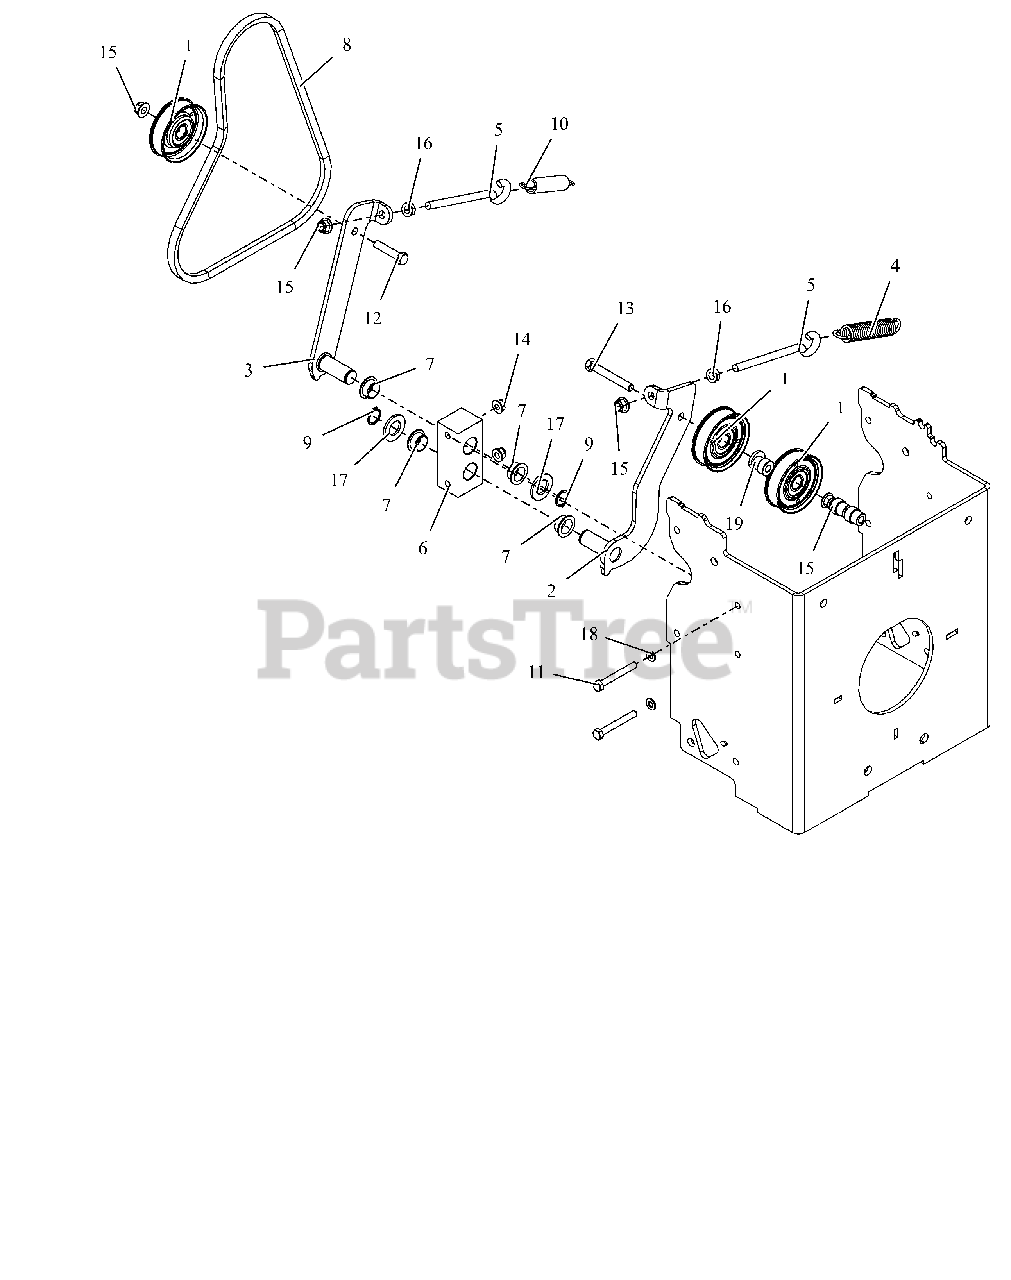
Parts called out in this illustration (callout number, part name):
1	IDLER, FLAT - 3.05" X .75"
2	WLDMT, TENSIONER PTO BELT
3	WLDMT, TENSIONER TRANS BELT
4	SPRG, EXTENSION
5	BOLT, EYE .38-16X4.50 .62DIABZ
6	BLOCK, BRG IDLER
7	BSHG, IDLER EP BB2012
8	V-BELT, HA-RAW EDGE
9	SNAP RING, .781 X .042 EXT
10	SPRING, EXT .091 X .75 X 3.75
11	BLT, HEX M8-1.25 X 65 G8.8 ZCC
12	BLT, HEX .38-16X1.75F G5 ZCC
13	BLT, HEX .38-16X2.75 G5 ZCC
14	NUT,NYL-FLG M8-1.25 G8.8 ZCC
15	NUT,NYL-FLG .38-16 GF ZCC
16	NUT, SPNLK-FLG .38-16 G5 ZCC
17	WSHR,FLT 21X37X3MM ZCC
18	WSHR,FLT .323X.625X.062 ZCC
19	WSHR,FLT .438X1.00X.160 ZCC
